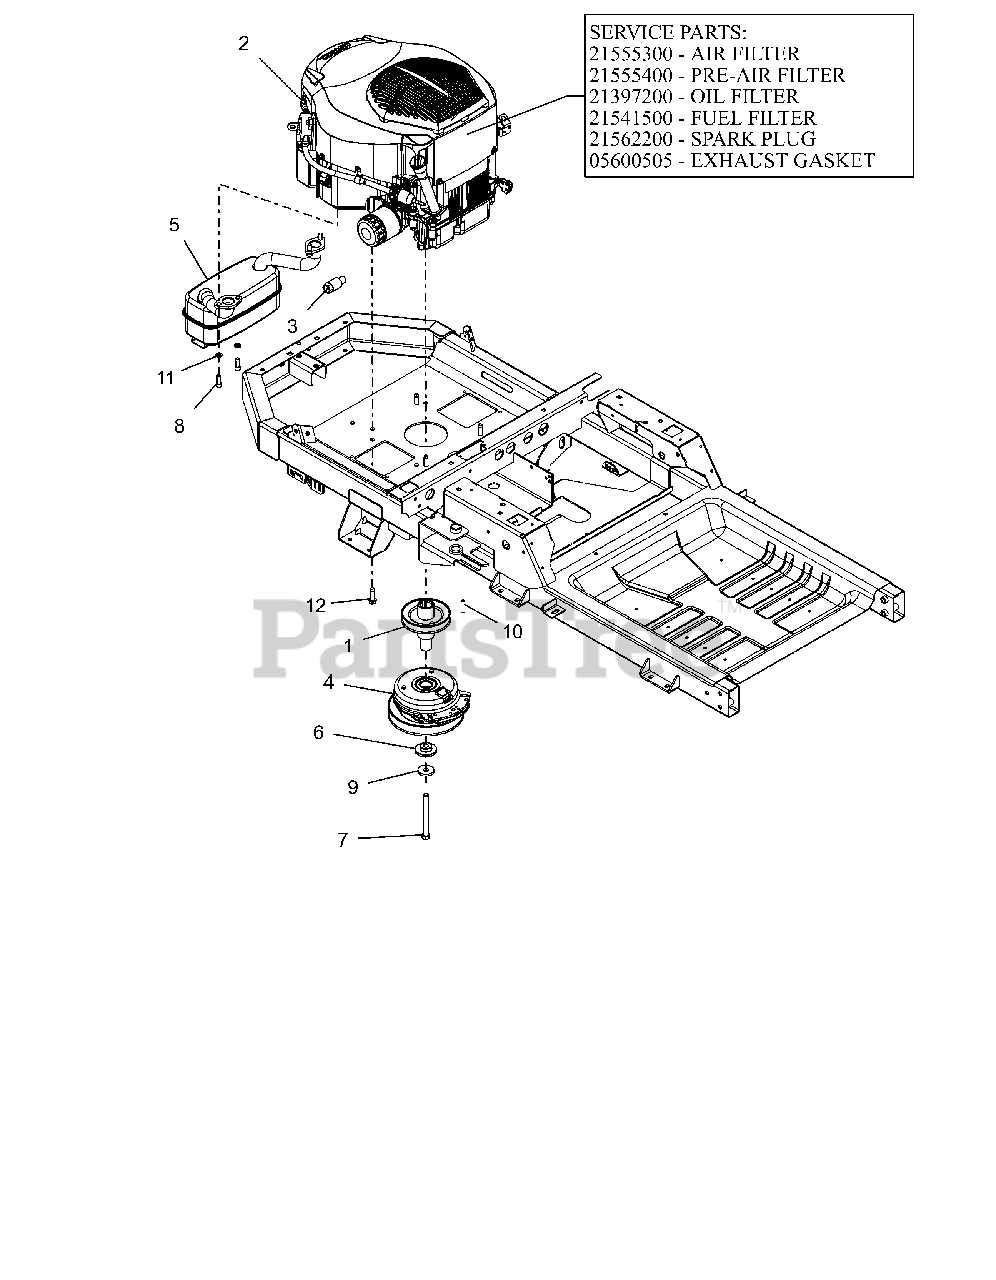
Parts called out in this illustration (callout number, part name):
1	WLDMT, DRIVE SHEAVE-X
2	ENGINE,KOHLER TWIN 25 PRO W/SC
2	AIR FILTER, KOHLER
2	PRE CLEANER, KOHLER
2	FILTER, OIL - KOH CV20
2	FILTER, FUEL
2	PLUG, SPARK (RFI)
2	GASKET, MUFFLER KOHLER TWIN
3	DRAIN, OIL
4	CLUTCH,105FTLB MONOPOLE 6.83"
5	MUFFLER - KOHLER
6	BSHG-FLG .469X1.06X.574X2.0
7	BLT, HEX .44-20X4.50 G8 ZCC NT
8	SCR, SKH .312-18X.875 GR8 ZCC
9	WASHER, 7/16" SPRING DISK
10	KEY-SQ .25 X 1.25 X .25 SAE
11	WSHR,LK-REG .312X.078 ZCC
12	SCR,TAP .375-16X1.25HWH TR ZCC
